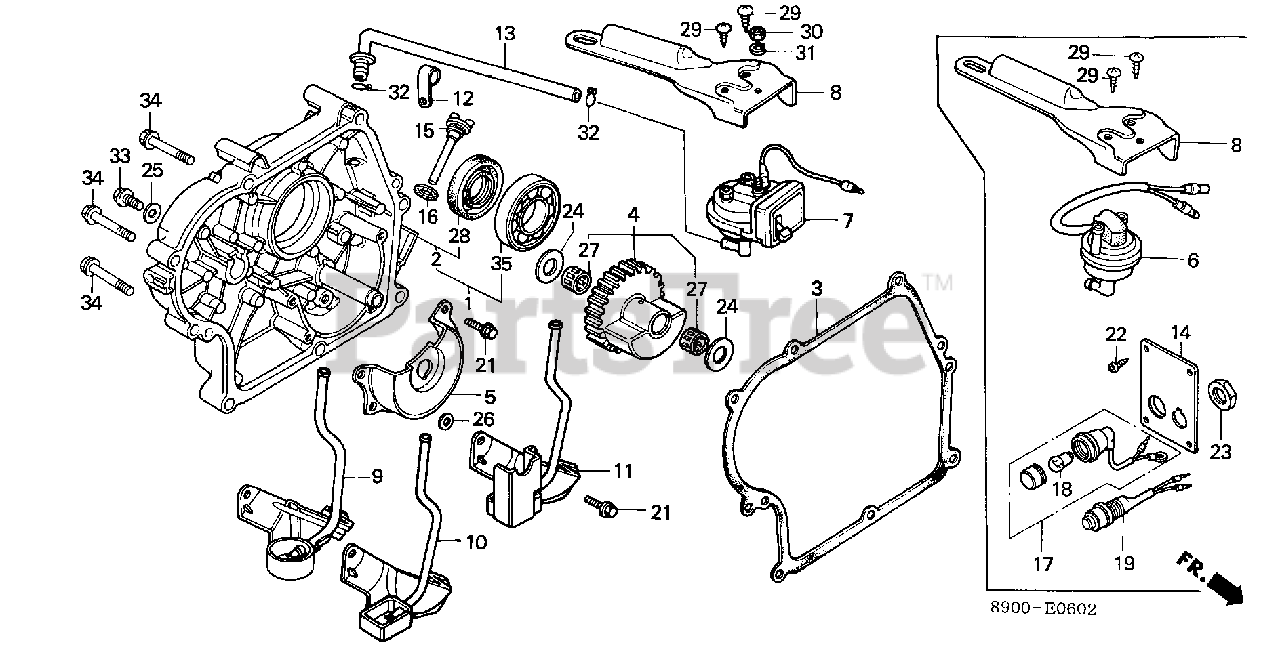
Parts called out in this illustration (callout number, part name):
2	COVER ASSY., CRANKCASE
3	GASKET, CASE COVER
4	WEIGHT, BALANCER
5	COVER, BALANCER
7	SWITCH ASSY., OIL ALERT UNIT
8	BRACKET, OIL ALERT UNIT SWITCH
12	CLAMP, TUBE
13	TUBE, OIL ALERT
15	CAP, OIL FILLER (YELLOW)
16	GASKET, OIL FILLER CAP
21	BOLT, FLANGE (6X16)
24	WASHER, THRUST (15MM)
25	WASHER A (8MM)
26	WASHER, CRANK ARM
27	BEARING, NEEDLE
28	OIL SEAL (30X46X8)
29	SCREW, TAPPING (5X10)
30	NUT, HEX. (5MM)
31	WASHER, SPRING (5MM)
32	CLIP, TUBE (C11)
33	BOLT, FLANGE (8X12)
34	BOLT, FLANGE (8X45)
